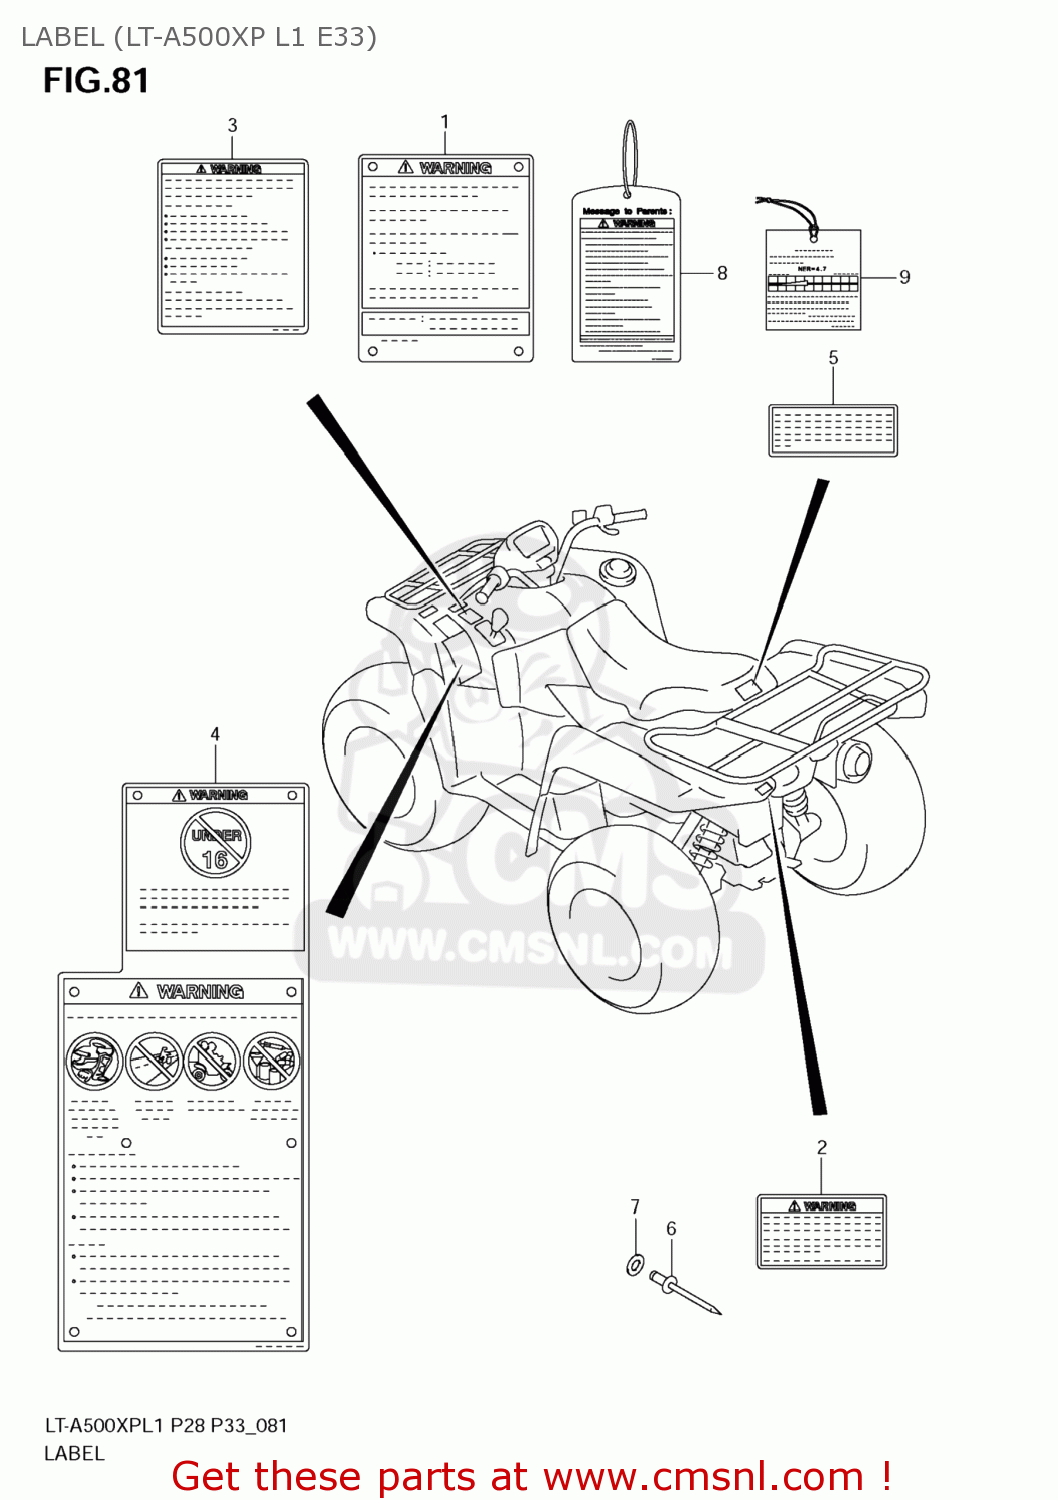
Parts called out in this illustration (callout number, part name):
1	LABEL,TIRE INFORMATION
2	LABEL,TRAILER TOW WARNING
3	LABEL,GEAR SHIFTING
4	LABEL,GENERAL WARNING & AGE 16
5	LABEL,MANUAL NOTICE
6	PIVET,WARNING LABEL
7	WASHER
8	TAG,ATV CATEGORY G
9	TAG,HANG
10	LT-A500XP 2011
